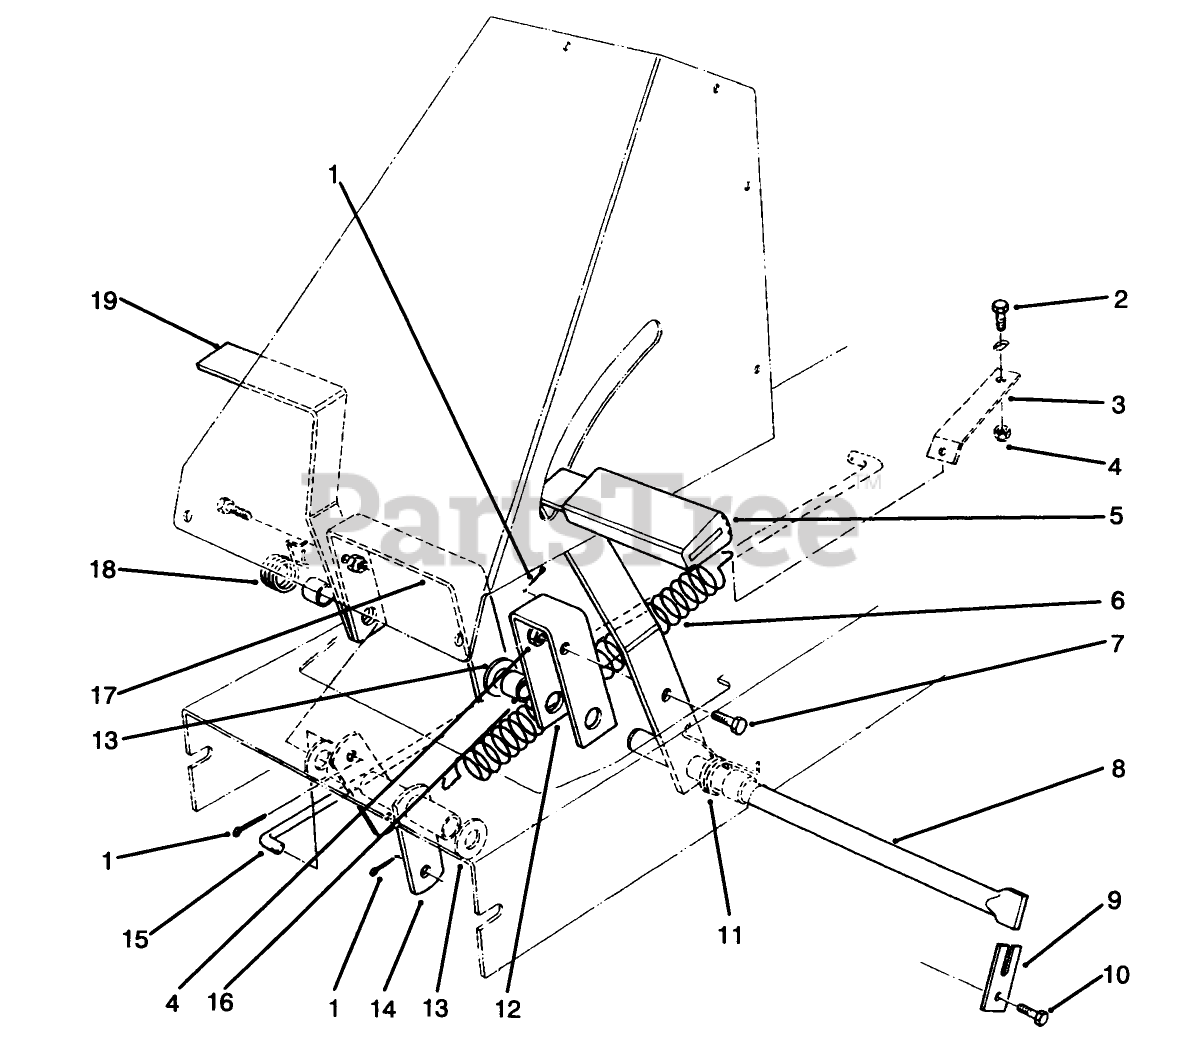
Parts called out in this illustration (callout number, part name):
1	PIN-COTTER
2	SCREW-HH
3	BRKT-SPRING RET
4	NUT-LOCK, NI
5	PAD-PEDAL
6	SPRING-EXTENSION
7	SCREW-HH
8	SHAFT-PEDAL PIVOT
9	RETAINER-SHAFT
10	SCREW-HH
11	SPRING-TORS CLUTCH
13	WASHER-FLAT
15	ROD-ENGAGE
16	SPACER-PEDAL
18	SPRING-TORS BRAKE
